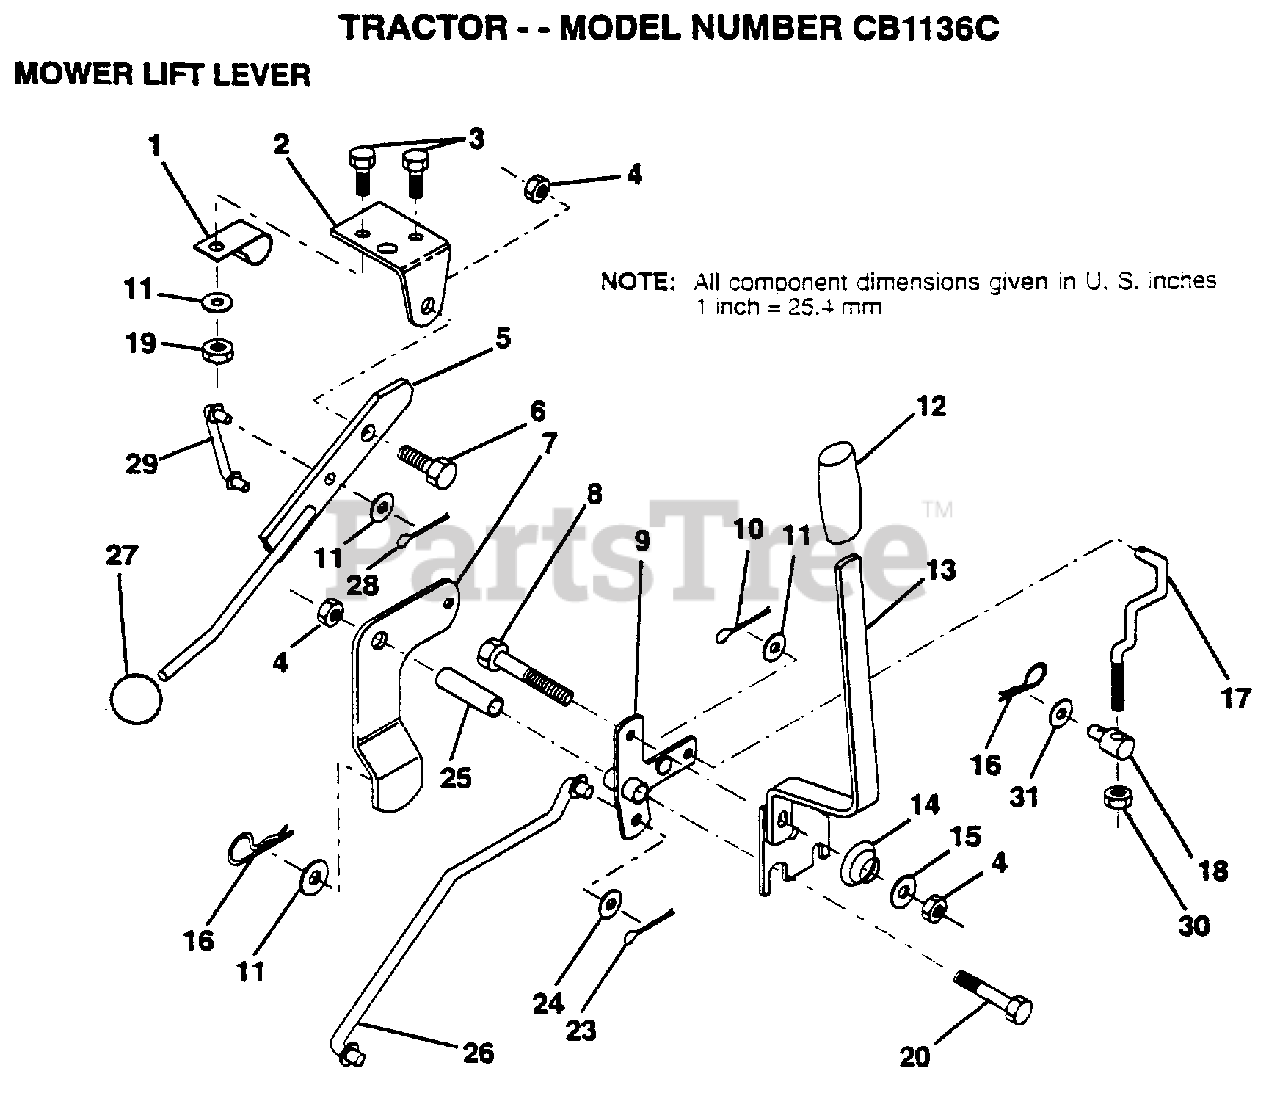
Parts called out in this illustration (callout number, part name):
1	"CLIP,INSULATOR"
2	BRKT CLUTCH
3	BOLT HXHD FIN
5	LEVER.ASM.CLUTCH
6	"BOLT, SHOULDER LT"
7	MWR CLUTCH ARM AS
8	BOLT
9	"BELLCRANK,LIFT"
10	COTTER PIN
11	WASHER
13	HANDLE.ASM.LIFT
14	SPRING COMPRESSIO
15	WASHER T
16	SPRING.RETAINER
17	"LINK,LIFT FRT"
18	TRUNION ADJ
20	BOLT
23	PIN COTTER 1/8
25	TUBE SPACER
26	ROD LIFT MOWER
27	KNOB T(3/8 HOLE)
29	CLUTCH LINK
30	NUT
31	WASHER
